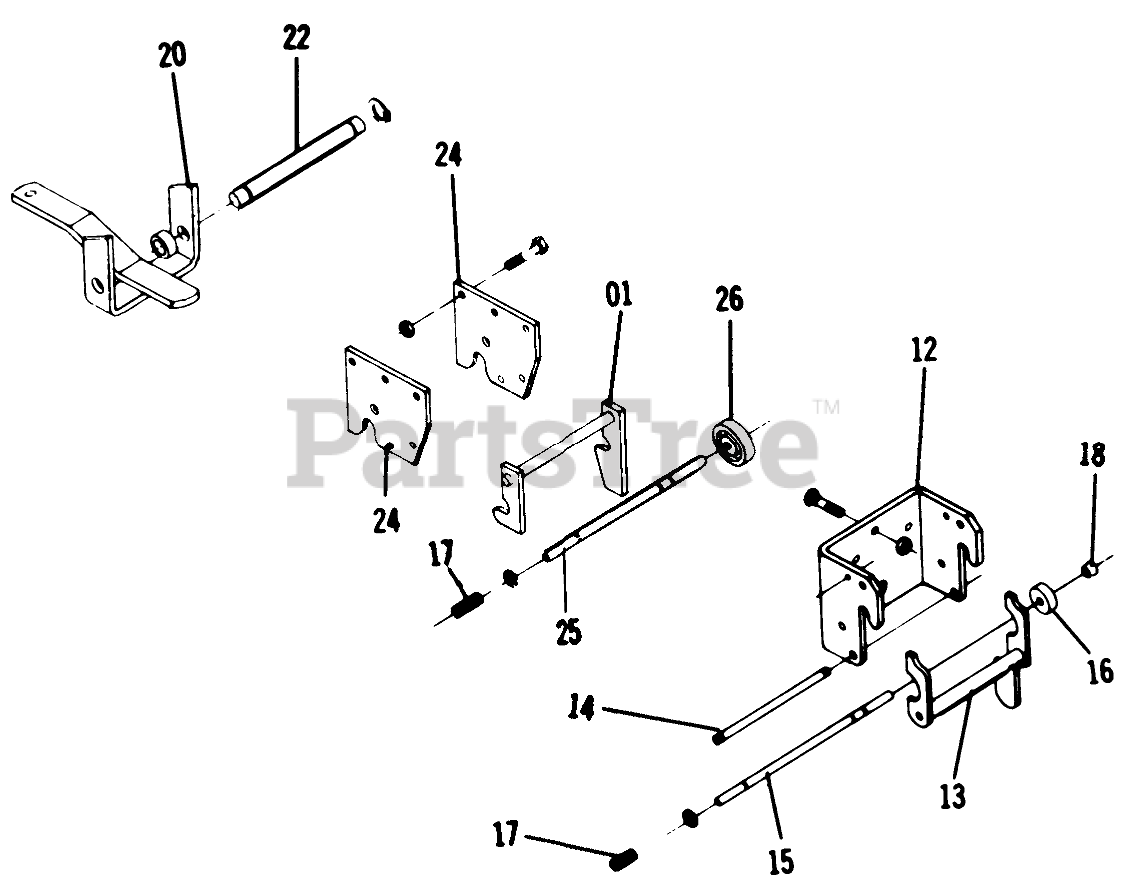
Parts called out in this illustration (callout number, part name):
7-01	ASSY MID HITCH LA R
7-12	Front Hitch
7-13	Latch Assembly
7-14	ROD-LATCH PIVOT
7-15	ROD-LOCK
7-17	SPRING
7-18	Cap
7-20	Hitch
7-22	Pin
7-24	Hitch Plate
